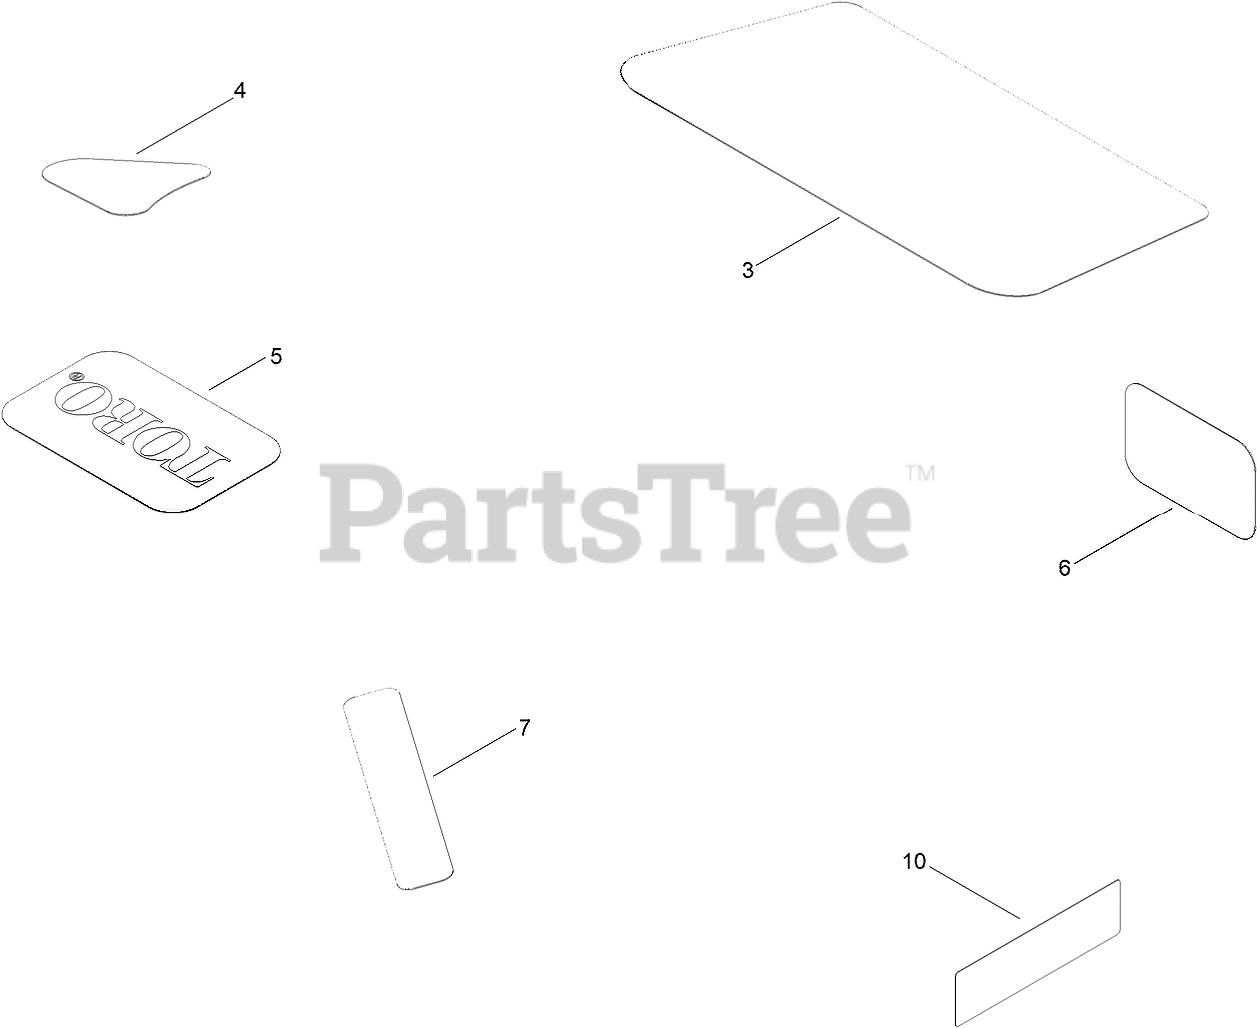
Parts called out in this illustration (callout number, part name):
3	DECAL-ENGINE
4	DECAL-DRAIN, OIL
6	PLACARD-INTAKE
7	DECAL-SHUTDOWN
